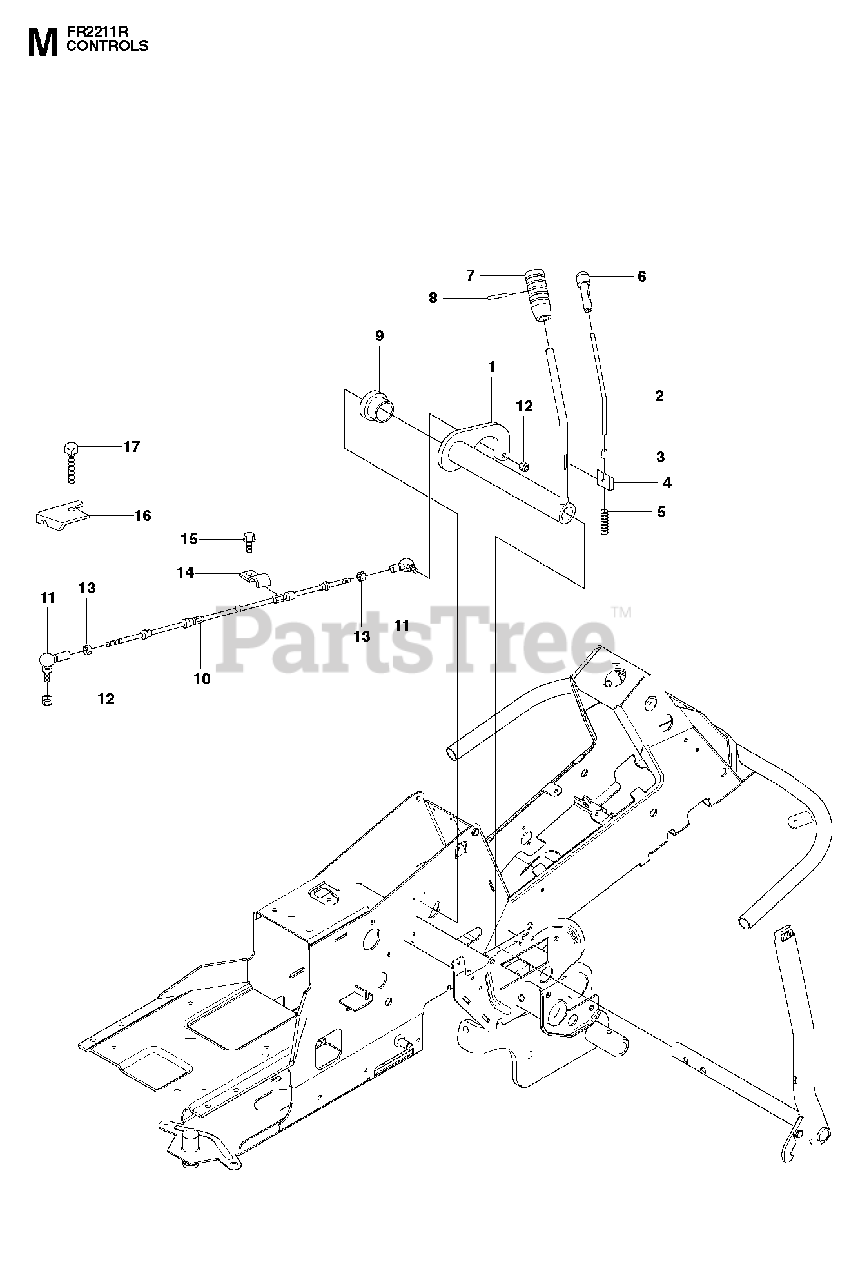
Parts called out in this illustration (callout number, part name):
3	END PIECE
8	SPRING PIN 3X24
9	BUSH
10	CONTROL CABLE
11	CONNECTOR
12	LOCKNUT M5
